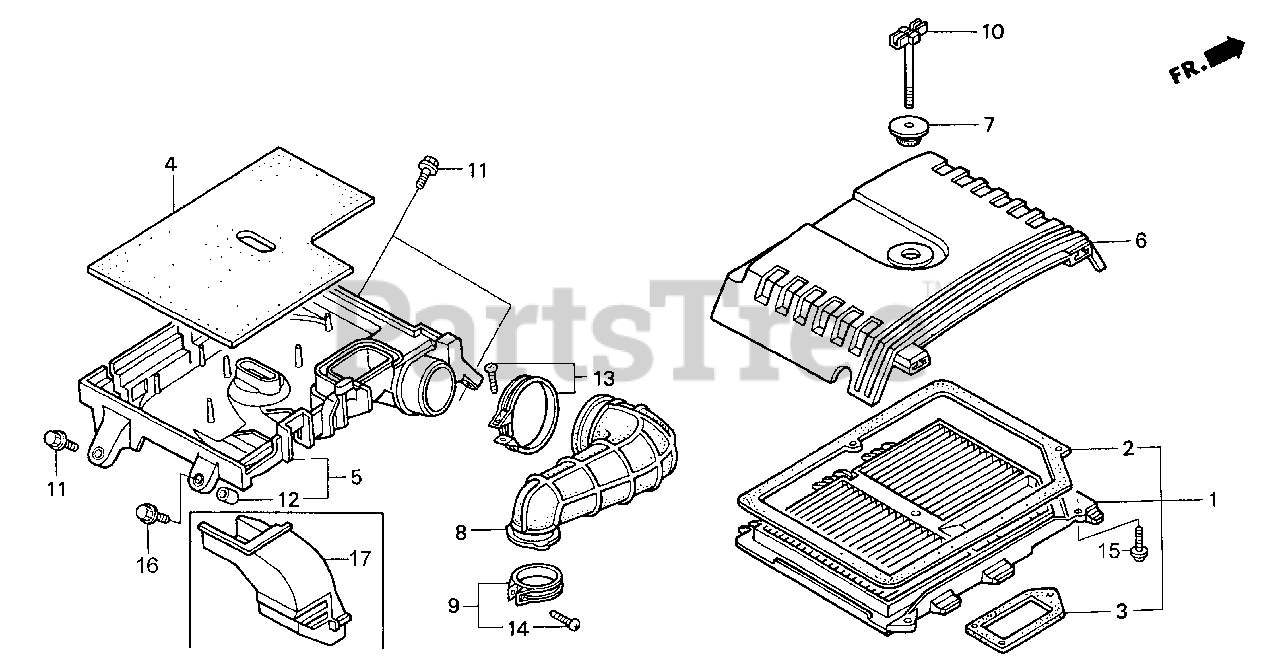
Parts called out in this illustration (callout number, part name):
1	ELEMENT SET, AIR CLEANER
2	GASKET A, ELEMENT
3	GASKET B, ELEMENT
4	FILTER (OUTER)
5	HOUSING, AIR CLEANER
6	COVER, AIR CLEANER
7	GROMMET, AIR CLEANER
8	TUBE, AIR CLEANER CONNECTING
9	BAND, AIR CLEANER CONNECTING TUBE
10	BOLT, AIR CLEANER
11	BOLT, FLANGE (6X23)
12	COLLAR, AIR CLEANER HOUSING
13	BAND, AIR CLEANER CONNECTING TUBE (50)
14	SCREW, PAN (4X20)
15	SCREW-WASHER (5X16)
16	BOLT, FLANGE (6X18)
17	HOSE, AIR CLEANER
